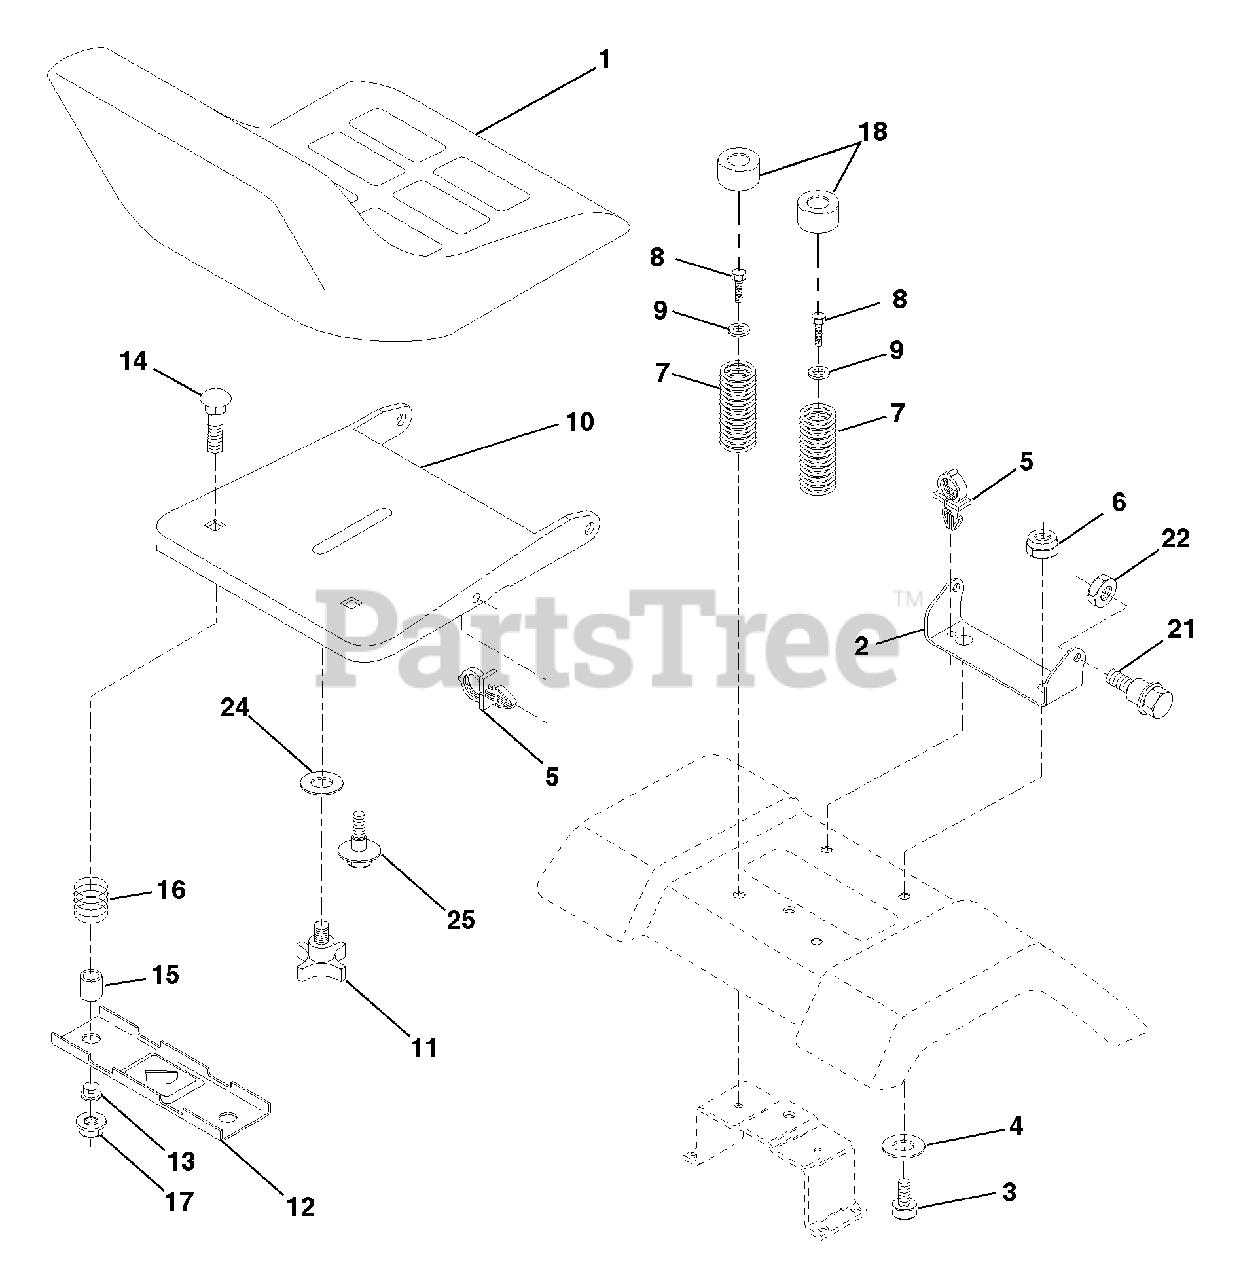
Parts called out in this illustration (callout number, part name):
1	Seat
2	Bracket Pivot Seat 8 720
3	Bolt Fin Hex 3/8-16unc X 1
4	Washer 13/32 X 1 X 10 Ga
5	Clip Push-In
6	Nut Hex w/Ins. 3/8-16 Unc
7	Spring Seat Cprsn 2 250 Blk Zi
8	Screw Thdrol 3/8-16 X 1 Ty-tt
9	Washer 13/32 X 1 X 14 Ga.
10	Pan Seat
11	Knob Seat 1/3-13 UNC Blk
12	Bracket Mounting Switch
13	Bushing Snap Blk Nyl 50 Id
14	Bolt Rdhd Sqnk 1/4-20 x 1-1/2
15	Spacer Split 28 x 96 Yel Zinc
16	Spring Cprsn 1 27 Blk Pnt
17	Nut Lock 1/4 Lge Flg Gr 5 Zinc
18	Cap Spring Seat
21	Bolt Shoulder 5/16-18 Unc
22	Nut Hex Lock W/Ins 5/16-18
23	Bolt, Hex Head, Fin 1/2-13 x 7/8 Grade 5
24	Washer 17/32 X 1-3/16 X 12 Ga.
25	Bolt Shoulder 5/16-18 X 62
26	Washer Lock
